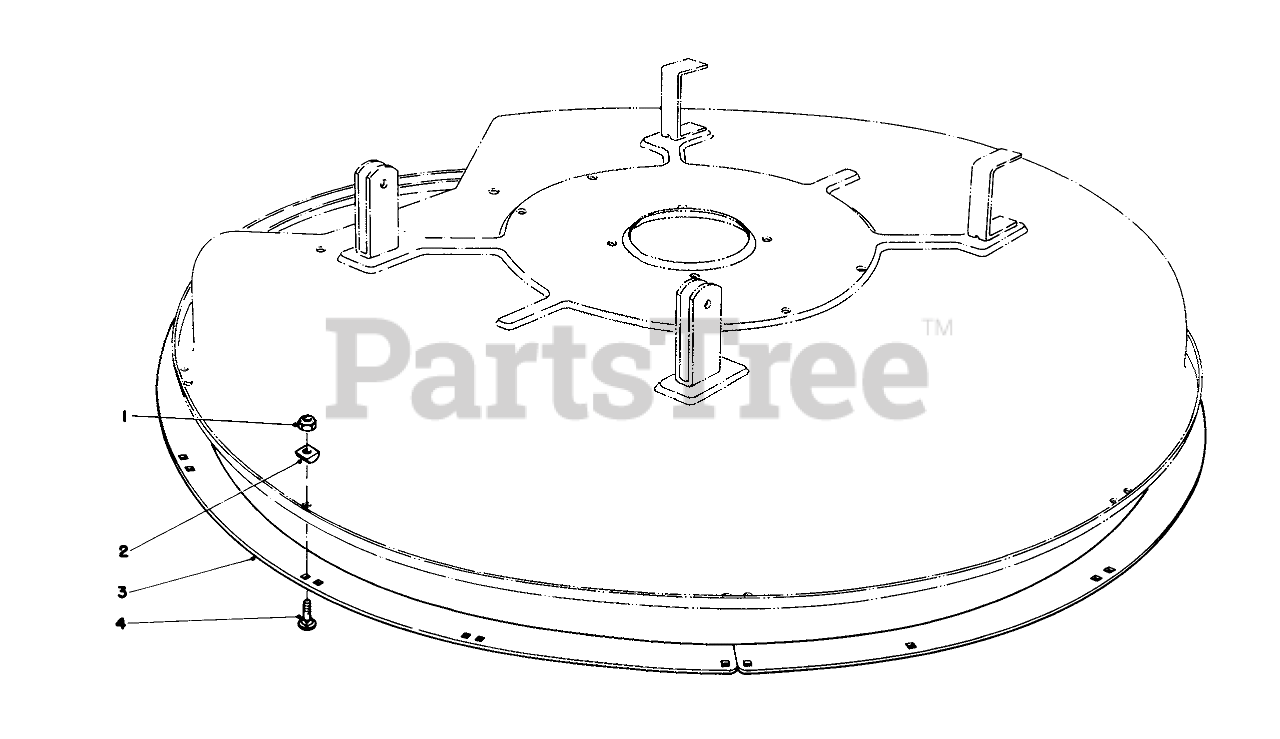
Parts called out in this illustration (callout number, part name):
1	NUT-LOCK, NI
2	DECK RING SPACER
3	DECK RING B
4	BOLT-CARR
